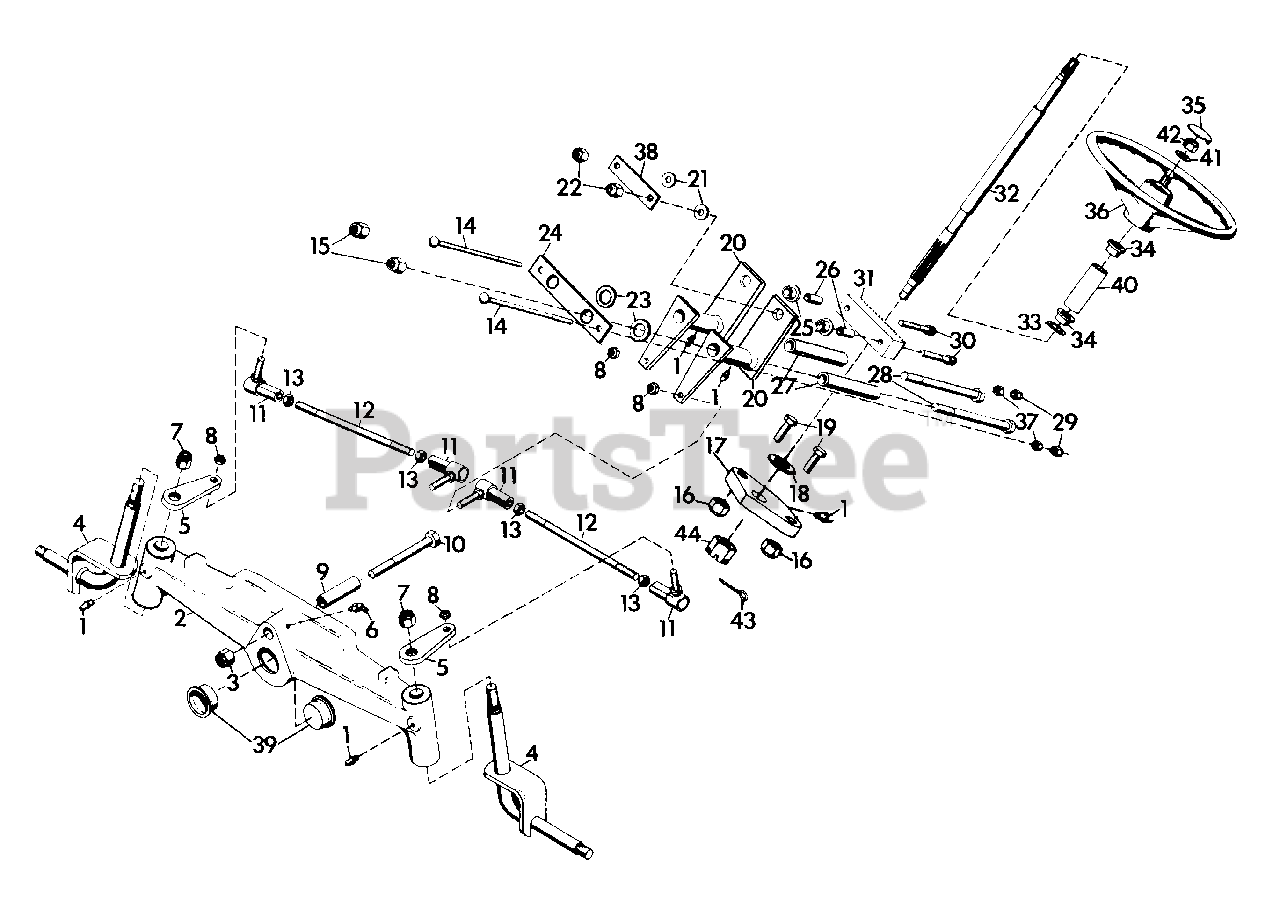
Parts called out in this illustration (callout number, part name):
1	FITTING, LUBE 1/4-28
2	ASSEMBLY, STEERING AXLE
3	NUT, LOCK 3/4-10
4	WELDMENT, KING PIN
5	ARM, TIE ROD
6	FITTING, LUBE 45 DEG.
7	NUT, HEX 5/8-11
8	NUT, LOCK 3/8-24
9	TUBE, AXLE PIVOT
10	BOLT, HEX 3/4-10X4.5
11	BALL JOINT, STEERING
12	ROD, STEERING TIE
13	NUT, HEX 3/8-24
14	BOLT, 5/16-18X5.5 RD HD SQ NK
15	NUT, LOCK 1/2-13
16	NUT, LOCK 7/16-14
17	SUPPORT, STEERING SHAFT
18	RACE, THRUST
19	BOLT, HEX 7/16-14X1.5
20	WELDMENT, STEERING ARM
21	WASHER, FLAT .375X1.125X.065
22	NUT, LOCK 3/8-16
23	RACE, BEARING THRUST .752X1.240X.095
24	PLATE, ADJUSTMENT
25	BEARING, FLANGE(P/M BRONZE)
26	BUSHING, .391X.622X.670
27	SLEEVE, PIVOT
28	BOLT, HEX 1/2-13X6.0
29	NUT, LOCK 5/16-18
30	SCREW, CAP 3/8-16X2.0 HEX SOCKET HD
31	GEAR, RACK
32	SHAFT, STEERING WHEEL
33	RING, RETAINING INT. TOOTH 1.000 SHAFT
34	BUSHING, NYLON .760X1.000X.600 FLANGE
35	CAP, STEERING WHEEL
36	WHEEL, STEERING 8122
36	WHEEL, STEERING 8123 AND 8163-B
37	NUT, HEX 5/16-18
38	STRAP, RACK AND PINION
39	CAP, FRONT AXLE
40	BUSHING, STEERING WHEEL
41	WASHER, FLAT .656X1.312X.095
42	NUT, JAM 5/8-11 HEX
43	PIN, COTTER .09X1.00
44	NUT, HEX 1/2-13 SLOTTED
